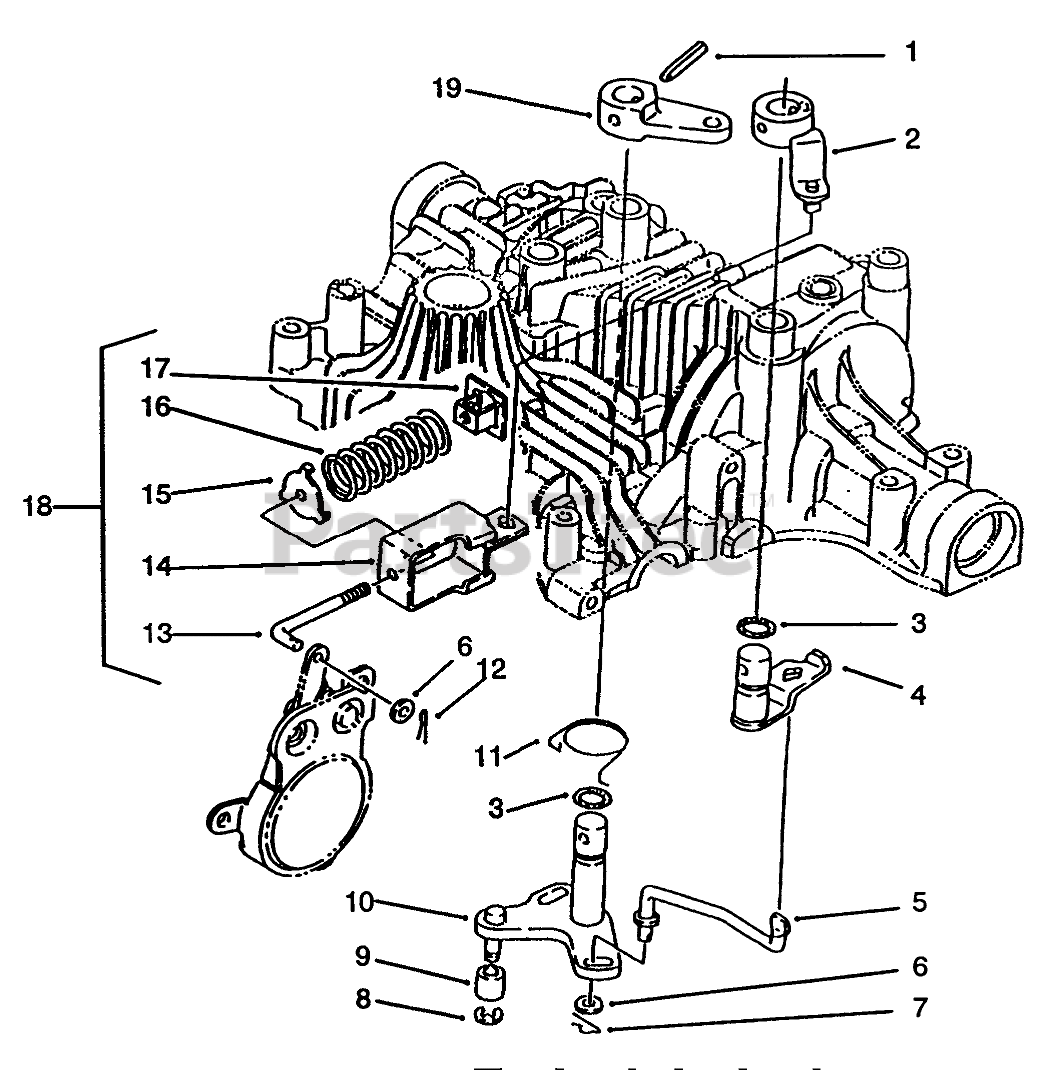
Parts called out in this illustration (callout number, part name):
1	Pin-Roll (Only On: 72083, 72043, 72103, 72063)
2	Arm-Brake B (Only On: 72083, 72043, 72103, 72063)
3	Packing (Only On: 72083, 72043, 72103, 72063)
4	Arm-Brake A (Only On: 72083, 72043, 72103, 72063)
5	Rod-Brake (Only On: 72083, 72043, 72103, 72063)
6	Washer (Only On: 72083, 72043, 72103, 72063)
7	Pin-Snap (Only On: 72083, 72043, 72103, 72063)
8	Ring (Only On: 72083, 72043, 72103, 72063)
9	Bushing (Only On: 72083, 72043, 72103, 72063)
10	Shaft-Brake (Only On: 72083, 72043, 72103, 72063)
11	Return-Brake (Only On: 72083, 72043, 72103, 72063)
12	Pin-Cotter (Only On: 72083, 72043, 72103, 72063)
13	Rod-Adjuster (Only On: 72083, 72043, 72103, 72063)
14	Holder-Spring (Only On: 72083, 72043, 72103, 72063)
15	Guide-Spring (Only On: 72083, 72043, 72103, 72063)
16	Spring (Only On: 72083, 72043, 72103, 72063)
17	Adjuster (Only On: 72083, 72043, 72103, 72063)
18	Rod ASM INC 13-17 (Only On: 72083, 72043, 72103, 72063)
19	Arm-Brake (Only On: 72083, 72043, 72103, 72063)
